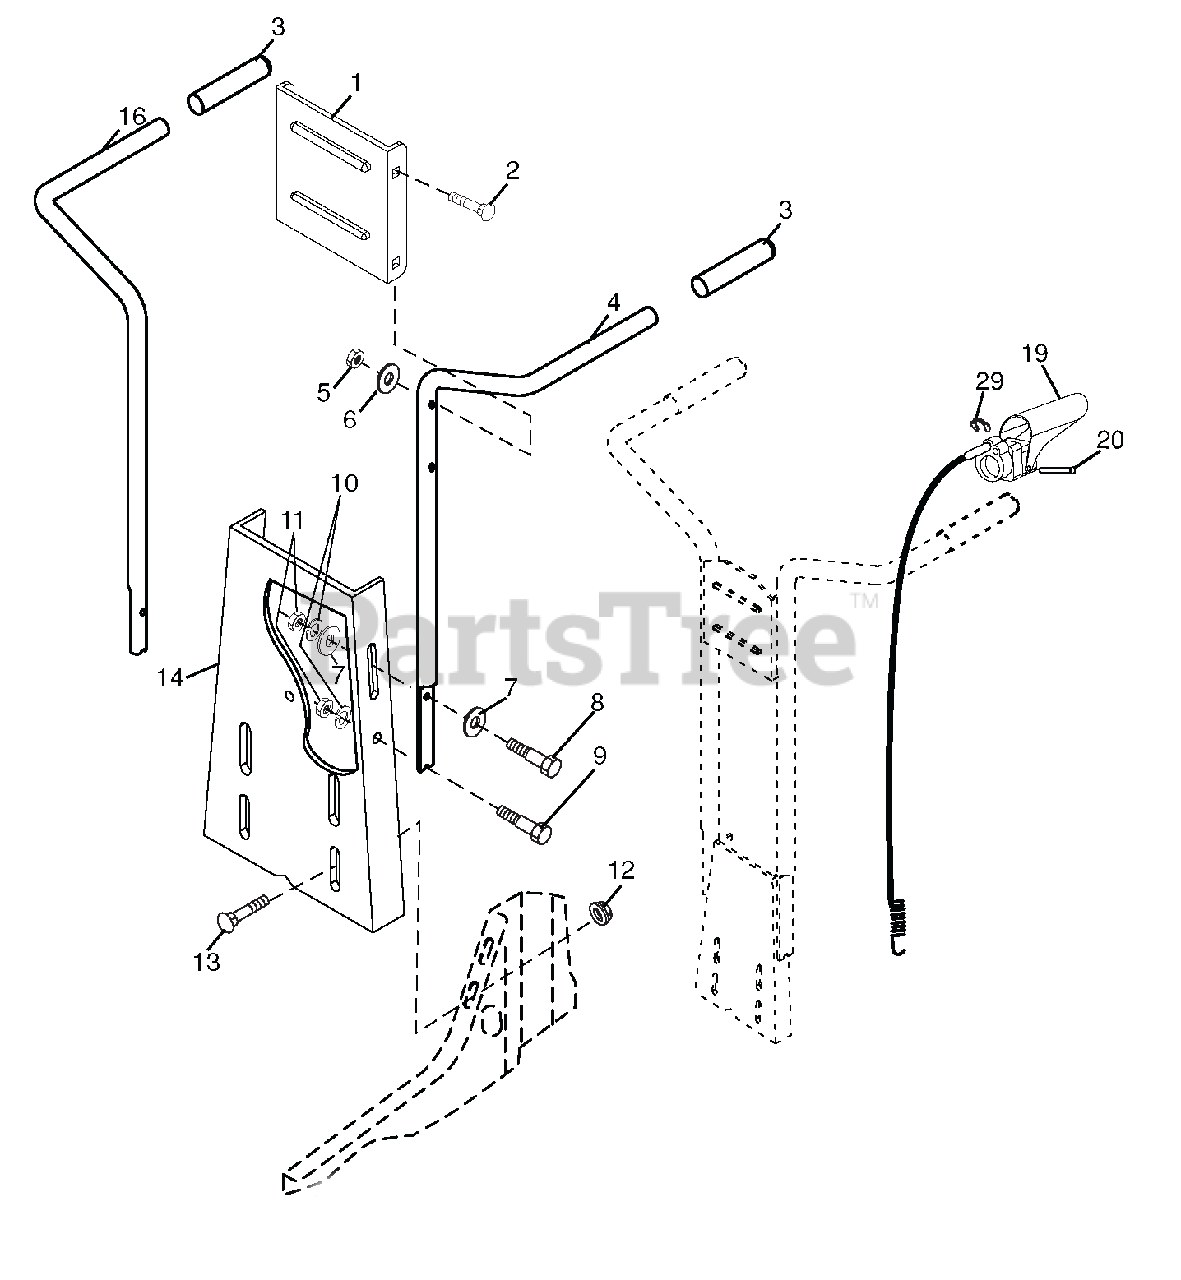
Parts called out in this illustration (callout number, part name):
1	Bracket, Handle
2	Bolt, Carriage 5/16-18 x 1-1/2
3	Grip, Handle
4	Handle, L.H.
5	Nut, Hex, Crownlock 5/16-18
6	Washer 11/32 x 11/16 x 16 Ga.
7	Washer 3/8 x 7/8 x 14 Ga.
8	Bolt, Hex Head 5/16-18 x 1-1/4
9	Bolt, Hex Head 5/16-18 x 1
10	Washer, Lock 5/16
11	Nut, Hex 5/16-18
12	Nut, Hex, Flanged 5/16-18
13	Bolt, Carriage, Gr. 5 5/16-18
14	Panel, Handle
16	Handle, R.H.
19	Tine Control Lever Assembly (I
20	Pin, Pivot
29	Retaining Ring
